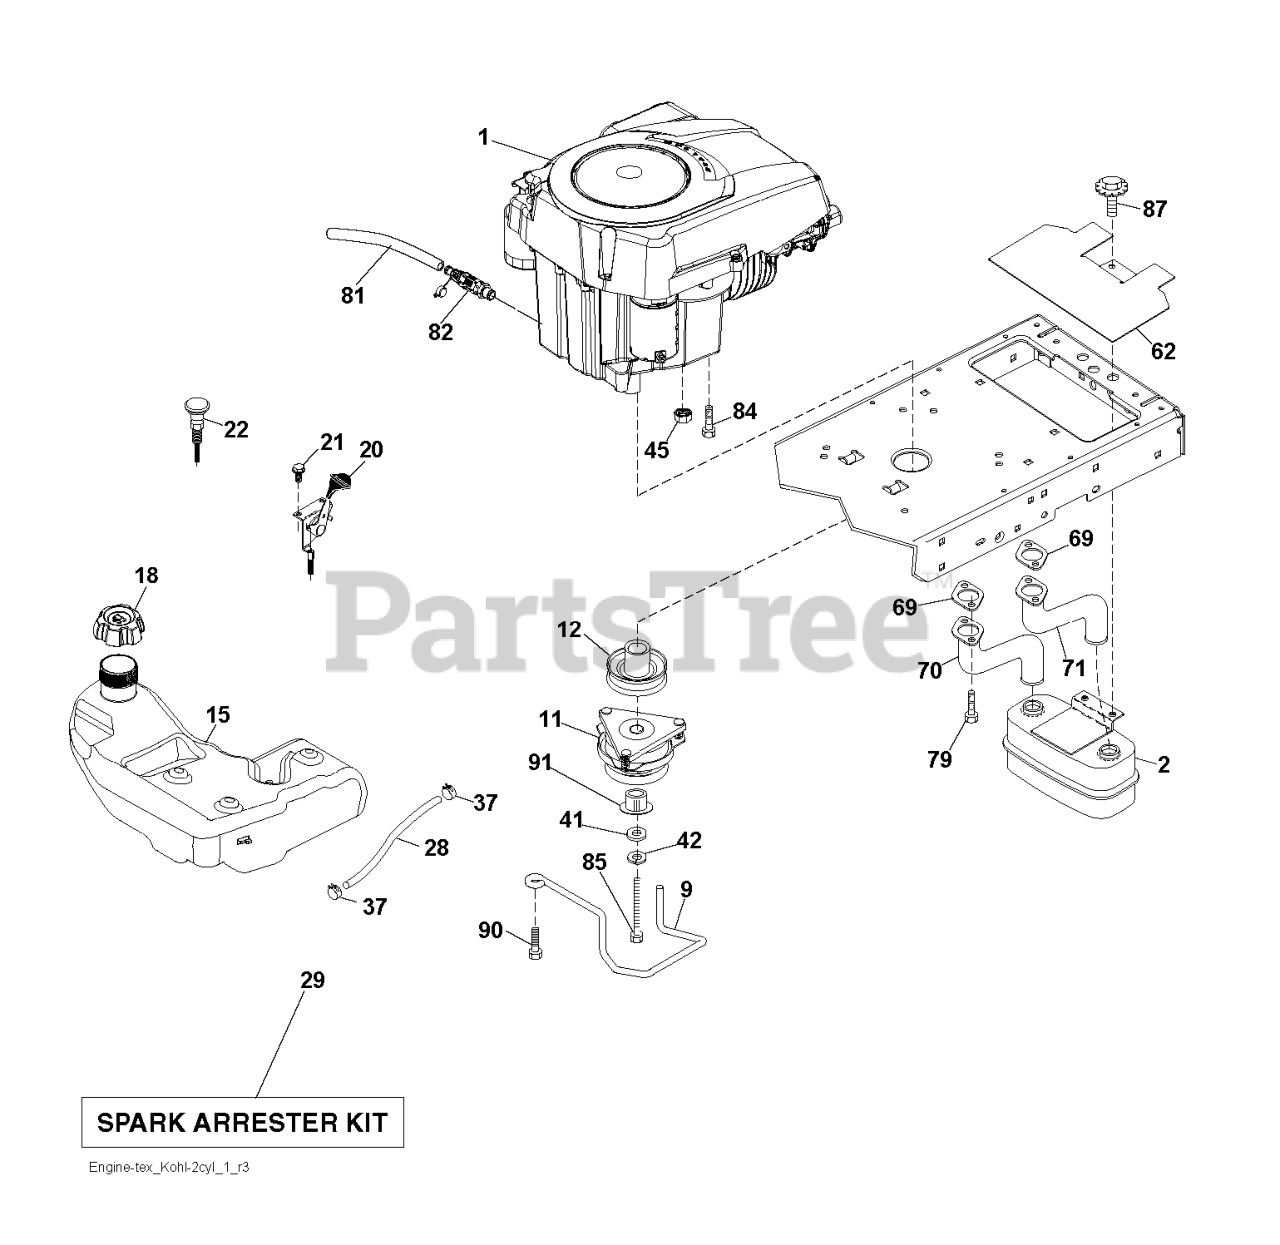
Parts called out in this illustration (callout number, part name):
2	MUFFLER.TWIN.CYL.LOW.TONE
9	KEEPER.BELT.ENGINE.4.2
11	CLUTCH MZ ZTR GT.48/54"1.125"
12	PULLEY ENGINE
15	TANK.FUEL.4GAL
18	CAP.FUEL.TANK.3"GREY
20	THROTTLE CONTROL
21	SCREW.#10 X 0.750.BOS
22	CONTROL.CHOKE.ERGO.PUSH-IN.BLA
28	REPL BY 532 00 85-43
29	KIT.SPARK ARRESTOR 794945 B&S
37	HOSE CLAMP
42	LOCKWASHER
45	NUT
62	RP SHIELD HEAT MUFFLER
69	GASKET.EXHAUST.KOHL.CV18-CV26
70	RP.PIPE-EXHAUST LH
71	RP.PIPE-EXHAUST RH
79	SCREW.SOCKET HD.5/16-1
81	TUBE, DRAIN OIL ASM.
82	VALUE.OIL.DRAIN
84	SCREW 3/8-16X1
85	BOLT HEX 7/16-20 X 3.75 GR. 5
87	BOLT.5/16-18UNCX3/4 W/SEMS.BLK
90	SCREW 3/8-16X1
91	BUSHING.1.375OD
